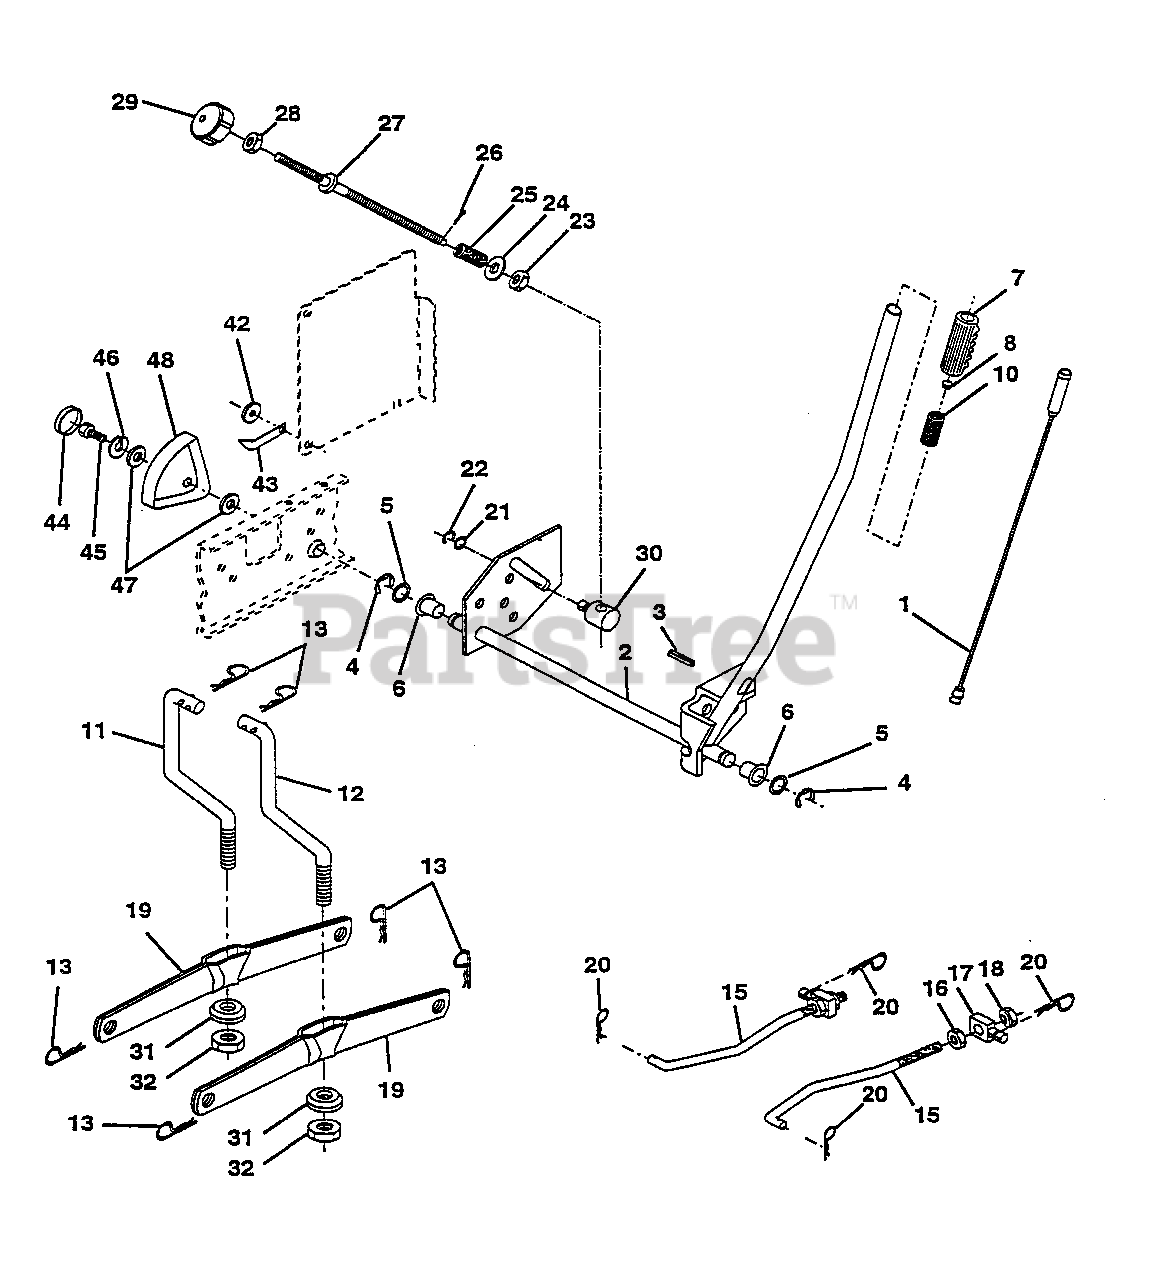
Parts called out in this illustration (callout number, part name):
1	Wire Asm Inner W/plunger 17 32
2	Shaft Asm Lift 93 RH
3	Pin Groove 1 500 Zinc
4	E Ring x5133-62
5	Washer 21/32 X 7/8 X 16 Ga
6	Bearing Nylon Blk 629 Id
7	Grip Handle Fluted Blk
8	Button Plunger Black
10	Spring Cprsn 3 750 Oiled
11	Link Lift LH
12	Link Lift RH
13	Retainer Spring
14	Pin Roll SLT 5/16 X 1 25 BLK O
15	Link Front
16	Nut Jam Hex 1/2-13 Unc
17	Trunnion Blk Zinc
18	Nut Lock W/wsh 1/2-13unc
19	Arm Suspension Rear
20	Retainer Spring
21	Washer 15/32 X 3/4 X 16 Ga
22	Ring Klip #t5304-37
23	Nut Special
24	Washer 13/32 X 5/8 X 16 Ga
25	Spring 2-1/8"
26	Pin Cotter 3/32 X 1/2
27	Rod Adj Lift Inc 9 00 Wrk Lg
28	Nut Hex Jam 3/8-16 Unc
29	Knob lnf 3/8-16 Unc BLK W/sym
30	Trunnion Dp Stop Dbl Thds PLT
31	Bearing pvt. Lift Spherical
32	3/8-24 Nylock Nut
42	Washer Nylon .44 x .75 x 032
43	Pointer pnt height ind.
44	Plug hole Blk 1.485/1.515 Dia
45	Bolt Fin hex 5/16-18 UNC x 1.00
46	Washer lock hvy hlcl spr. 5/16
47	Washer 11/32 x 1-1/2 10 Ga
48	Scale Ind. Height Black
